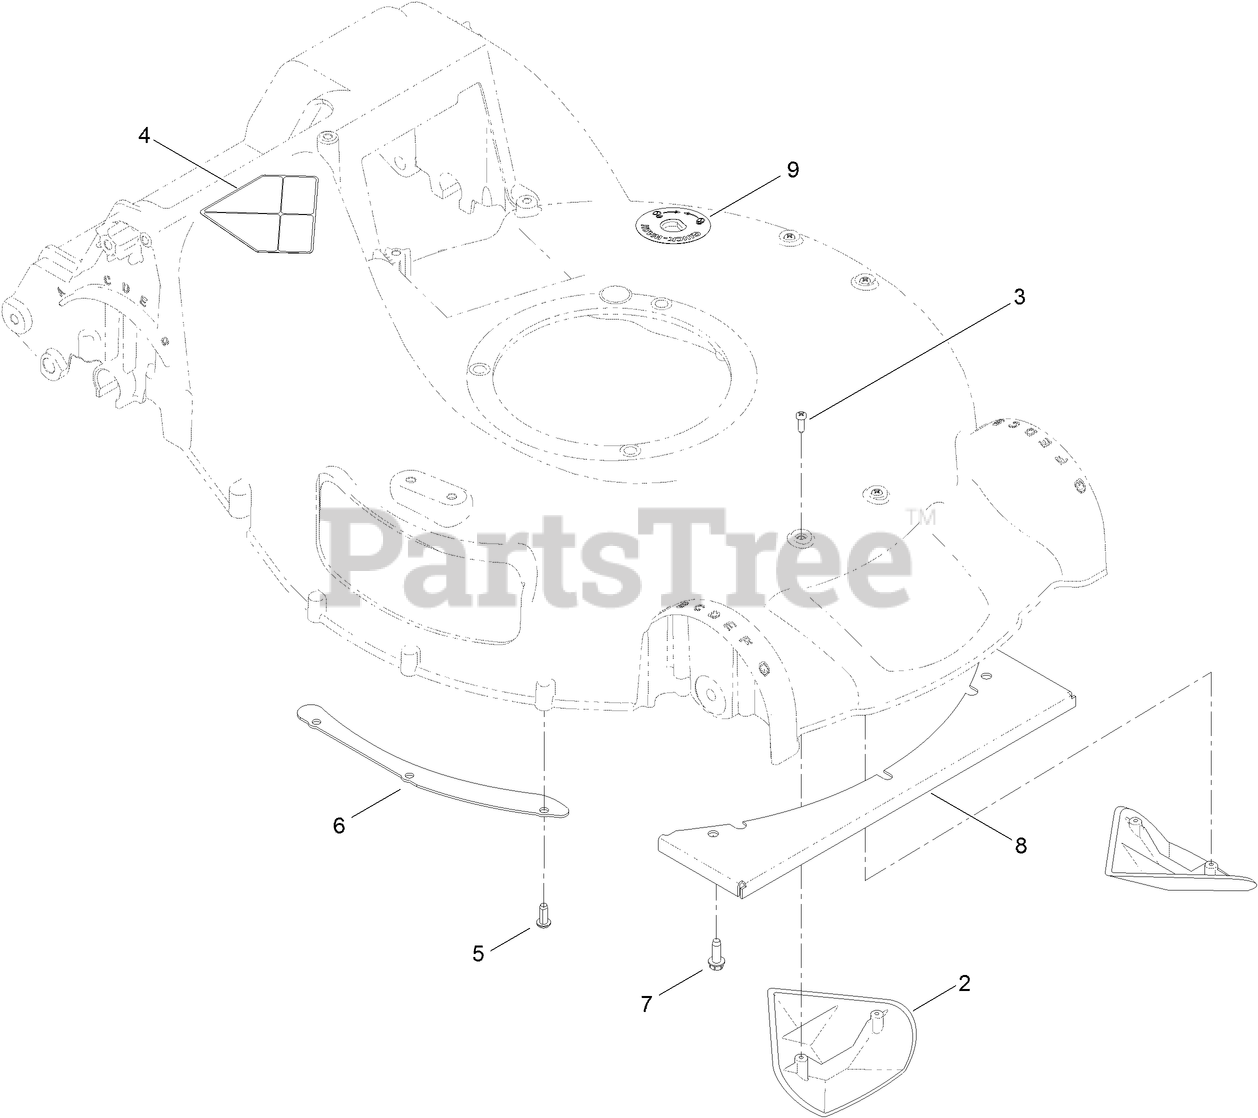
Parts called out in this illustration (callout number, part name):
2	KICKER-HOUSING
3	SCREW-PPH
4	DECAL-DANGER
5	SCREW
6	SHEET-LIP
7	SCREW-HWHTF
8	PLATE-COVER, FRONT
9	DECAL-PORT, WASHOUT
